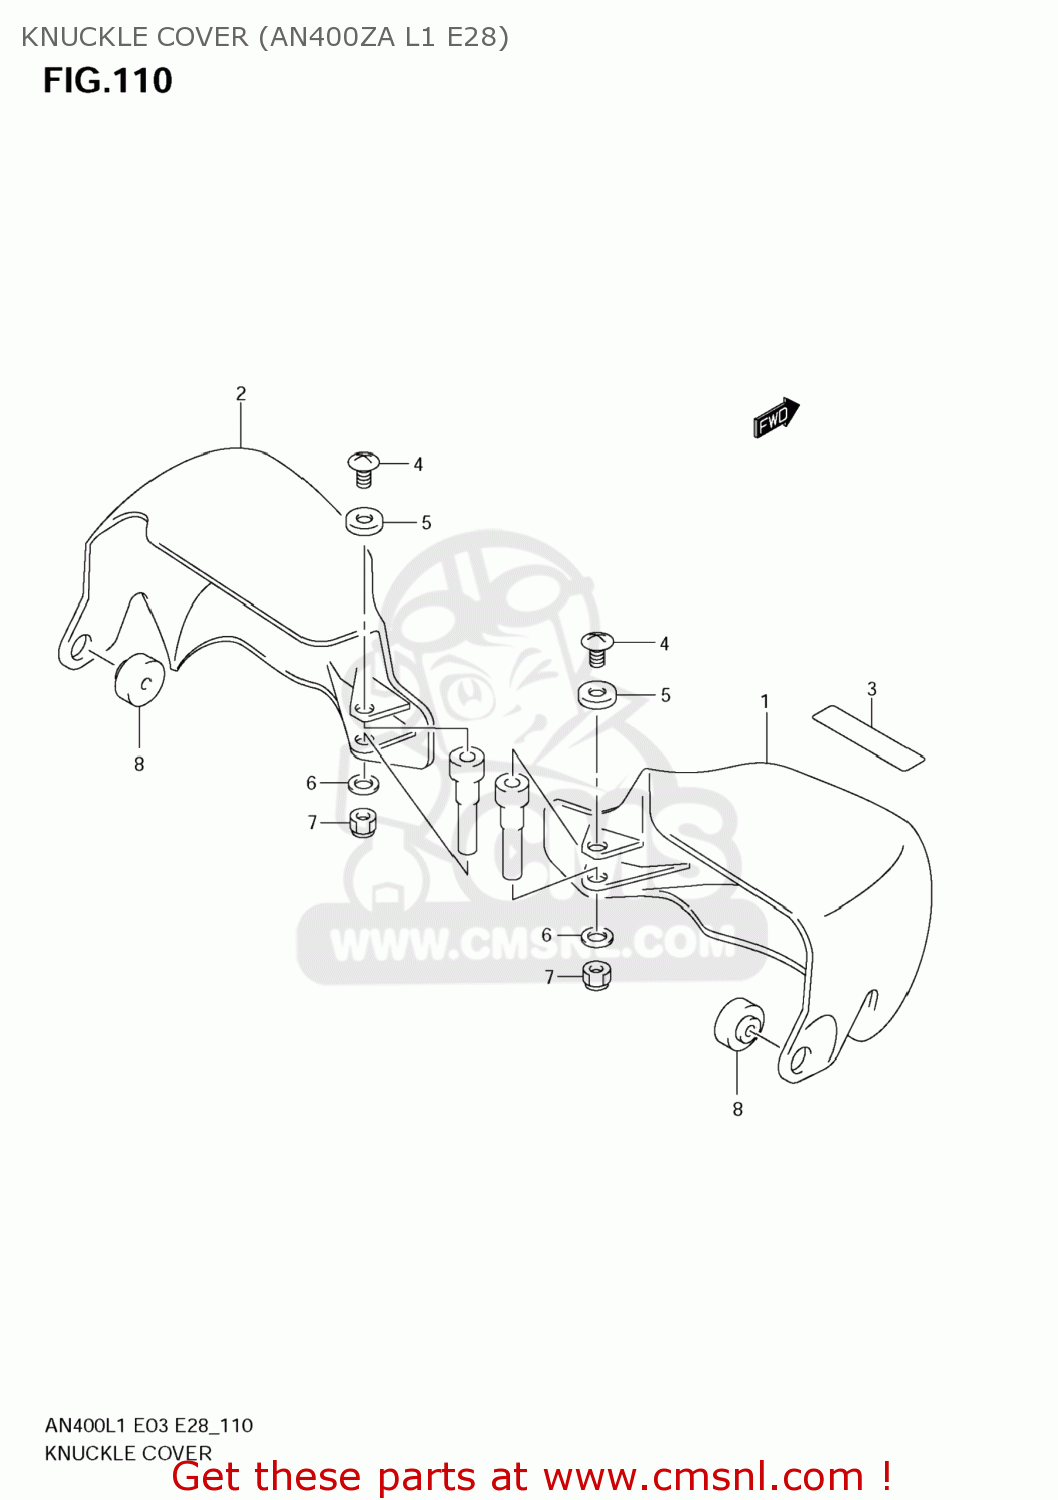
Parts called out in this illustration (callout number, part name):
1	COVER,KNUCKLE,R
2	COVER,KNUCKLE,L
3	TAPE,COVER
4	SCREW
5	PLATE,KNUCKLE COVER
6	WASHER(6.5X16X1.6)
7	NUT
8	SPACER,KNUCKLE COVER
